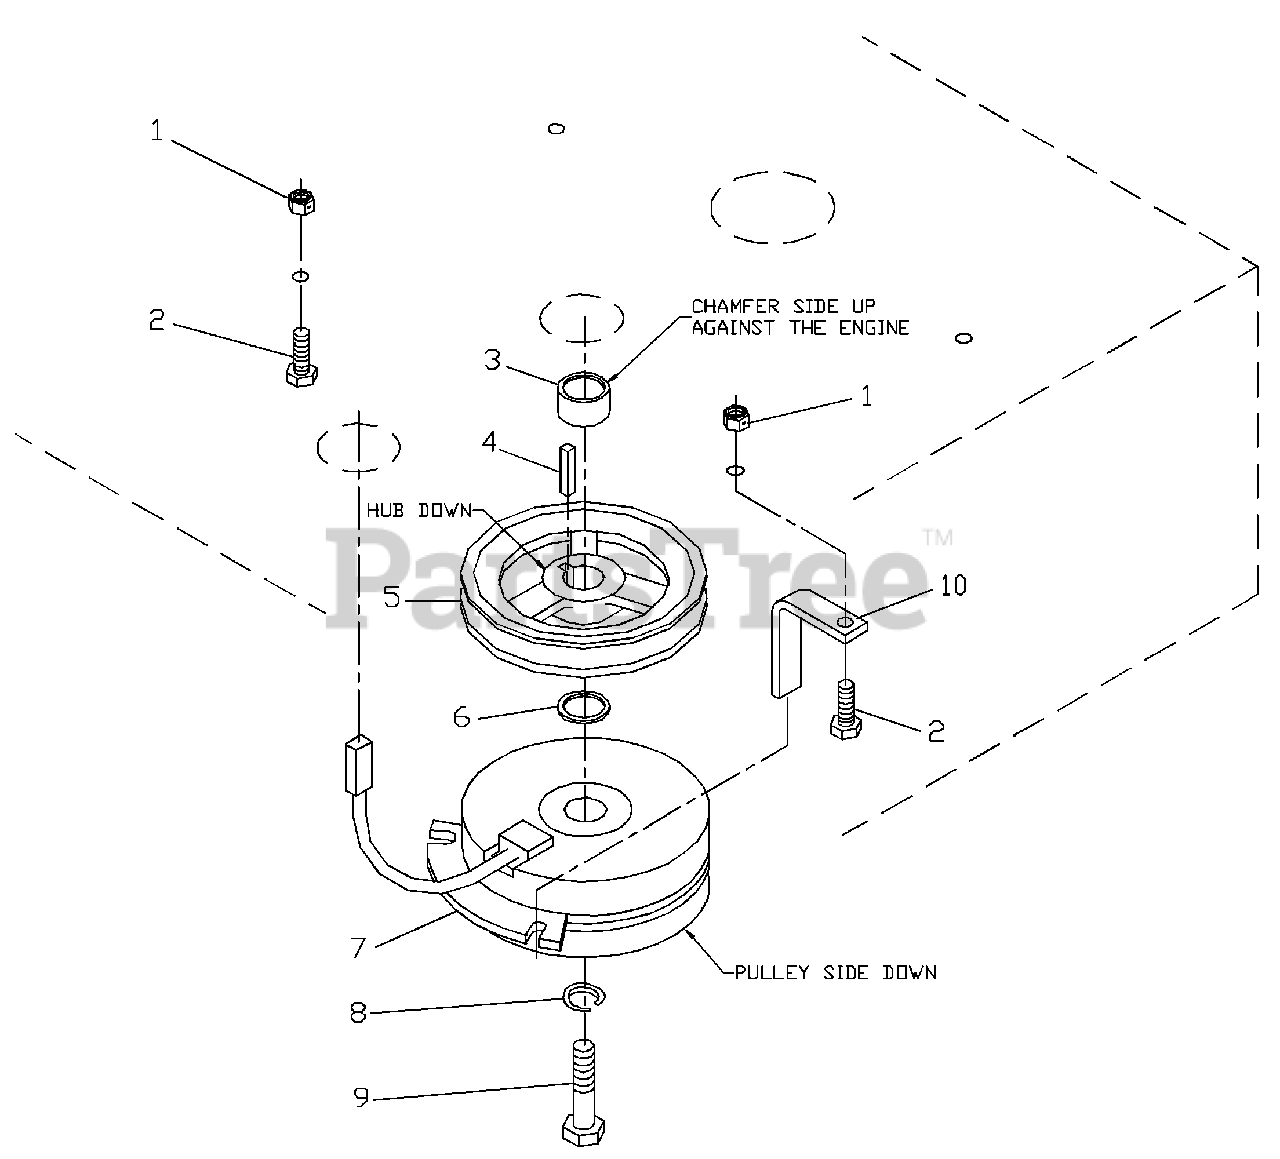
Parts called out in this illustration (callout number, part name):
1	NUT 5/16C CENTERLOCK
2	HCS 5/16C X 1 3/4
4	KEY 1/4 SQ. X 1 1/8
6	10GA. MACHINERY BUSHING
7	ELECTRIC CLUTCH
8	7/16 LOCKWASHER
9	HCS 7/16F X 2 1/2
10	CLUTCH TIE DOWN
